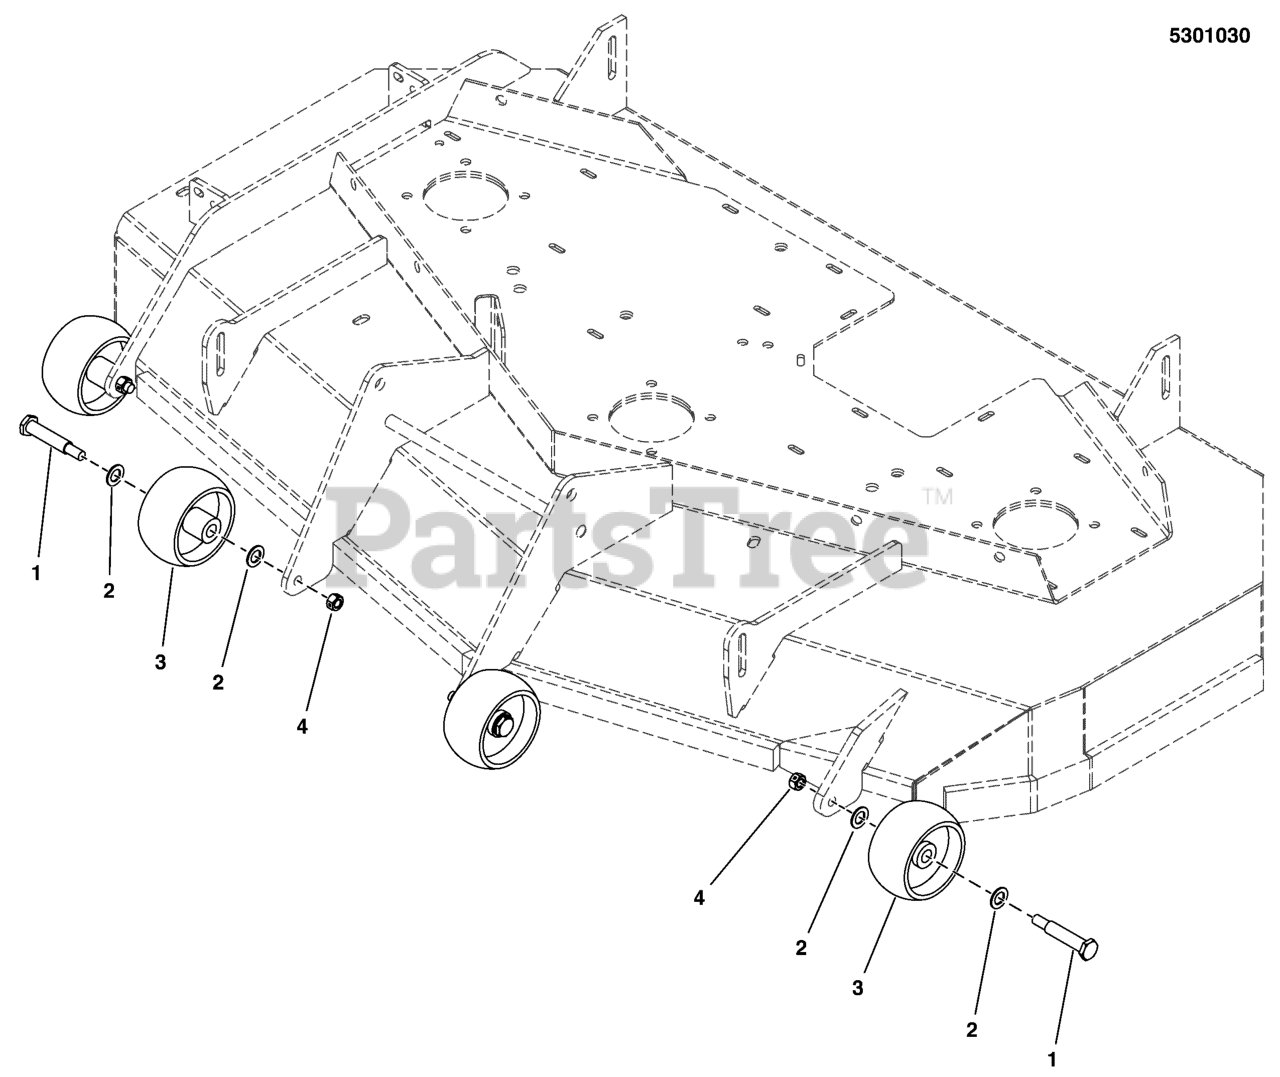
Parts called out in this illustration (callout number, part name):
1	BOLT-WHEEL 3/8-16X2.781 .750 THRD
2	WASHER,.516IDX.875ODX.06,FLAT,ZC/CL
3	WHEEL- 2.00 WIDE 3.88 DIA 0.531ID POLY
4	NUT, 3/8-16 HEX SIDE LOCK
